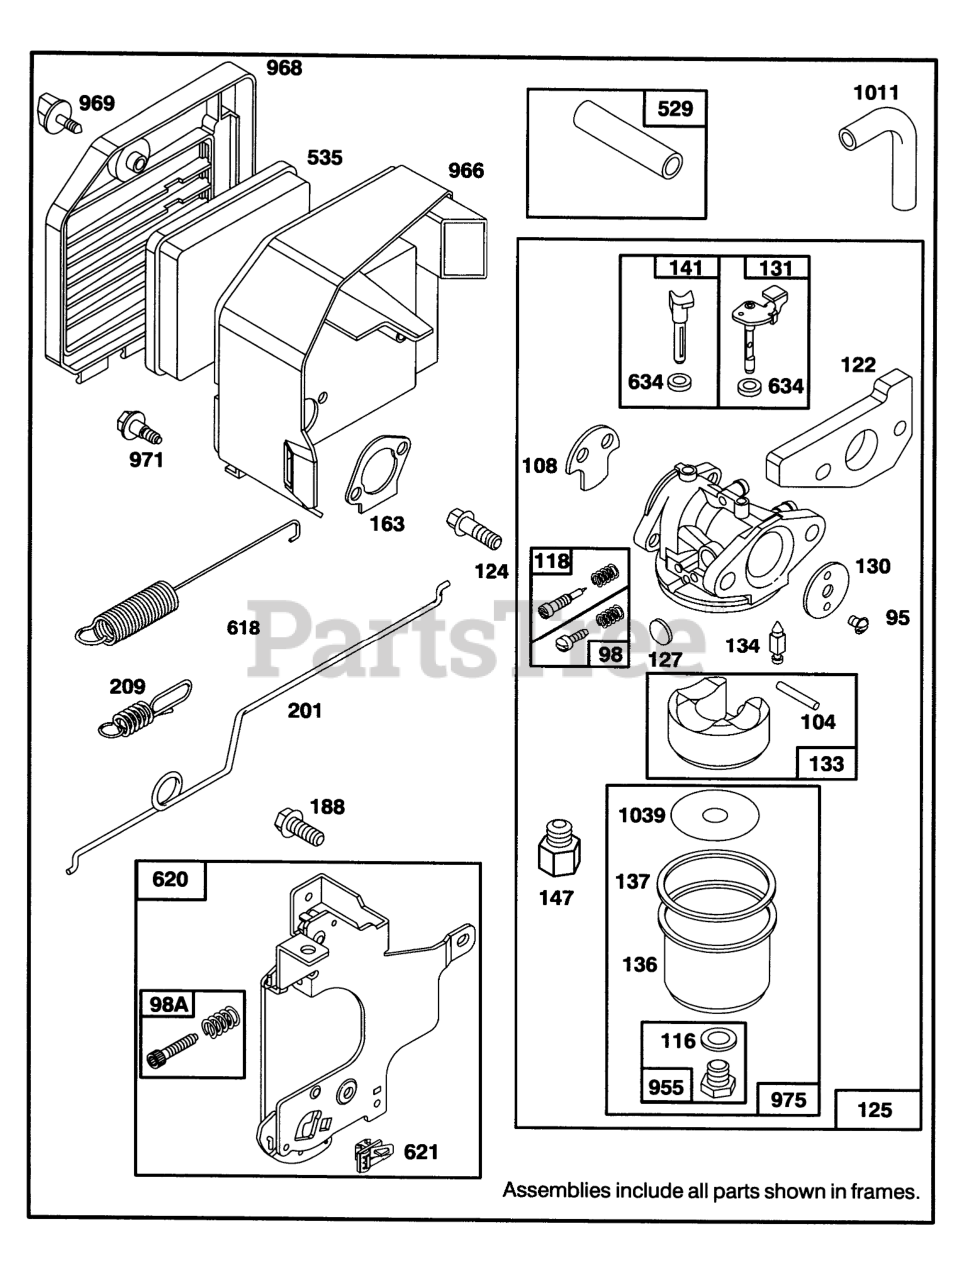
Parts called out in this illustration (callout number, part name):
95	SCREW - ROUND HEAD
98	IDLE ADJUSTING SCREW
98A	SPEED ADJUST. SCREW ASM
104	FLOAT HINGE PIN
108	CHOKE VALVE
116	SEALING GASKET
118	VALVE KIT - NEEDLE
122	ADAPTER ASSEMBLY
124	HEX HEAD SCREW
125	CARBURETOR ASSEMBLY
127	PLUG
130	THROTTLE VALVE
131	THROTTLE SHAFT
133	FLOAT-CARBURETOR
134	Valve-Float (Includes Seat)
136	FLOAT BOWL
137	FLOAT BOWL GASKET
141	CHOKE SHAFT
147	JET ADAPTER
163	AIR CLEANER GASKET
188	SCREW - SEM
201	GOVERNOR LINK
209	GOVERNOR SPRING
529	BREATHER TUBE
535	FILTER ELEMENT
618	RETURN SPRING
620	CARBURETOR BRACKET
621	STOP SWITCH
634	SEAL WASHER
955	HEX HEAD SCREW
966	AIR CLEANER BASE
968	AIR CLEANER COVER
969	AIR CLEANER SCREW
971	AIR CLEANER SCREW
975	CARBURETOR BOWL ASM
1011	VENT TUBE
1039	FLOAT LIMITER
